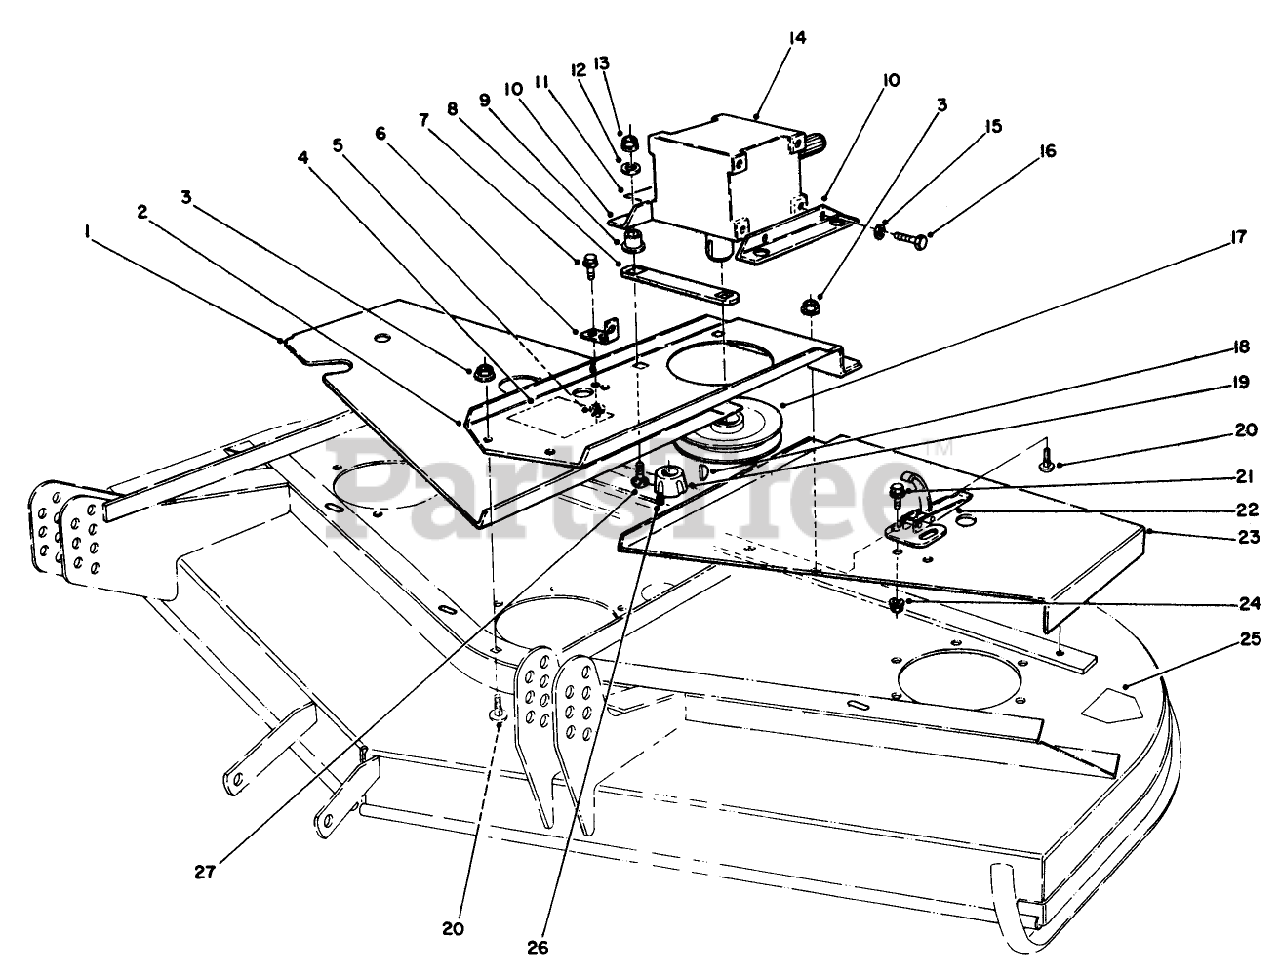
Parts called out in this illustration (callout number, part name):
1	Cover RH
2	Base-Gear Box
3	NUT-HHF, WHIZ
4	DECAL
5	NUT-HF
6	Bracket-Extension
7	SCREW-HH
8	Cover-Gear Box
9	MOUNT
10	Bracket-Gearbox
11	DECAL-OIL
12	WASHER
13	NUT-LOCK, SIDE
14	Gearbox
15	WASHER-LOCK
16	SCREW-HH
17	PULLEY
18	KEY-WOODRUFF
19	Bushing-Taper Lock (Incl. Ref. #26)
20	SCREW-CARR
21	SCREW-HWH
22	CLAMP-SLOTTED
23	Cover LH
24	NUT-LOCK, FLANGE
25	DECAL-DANGER
26	SCREW-SET, HSH
27	SCREW-CARR
